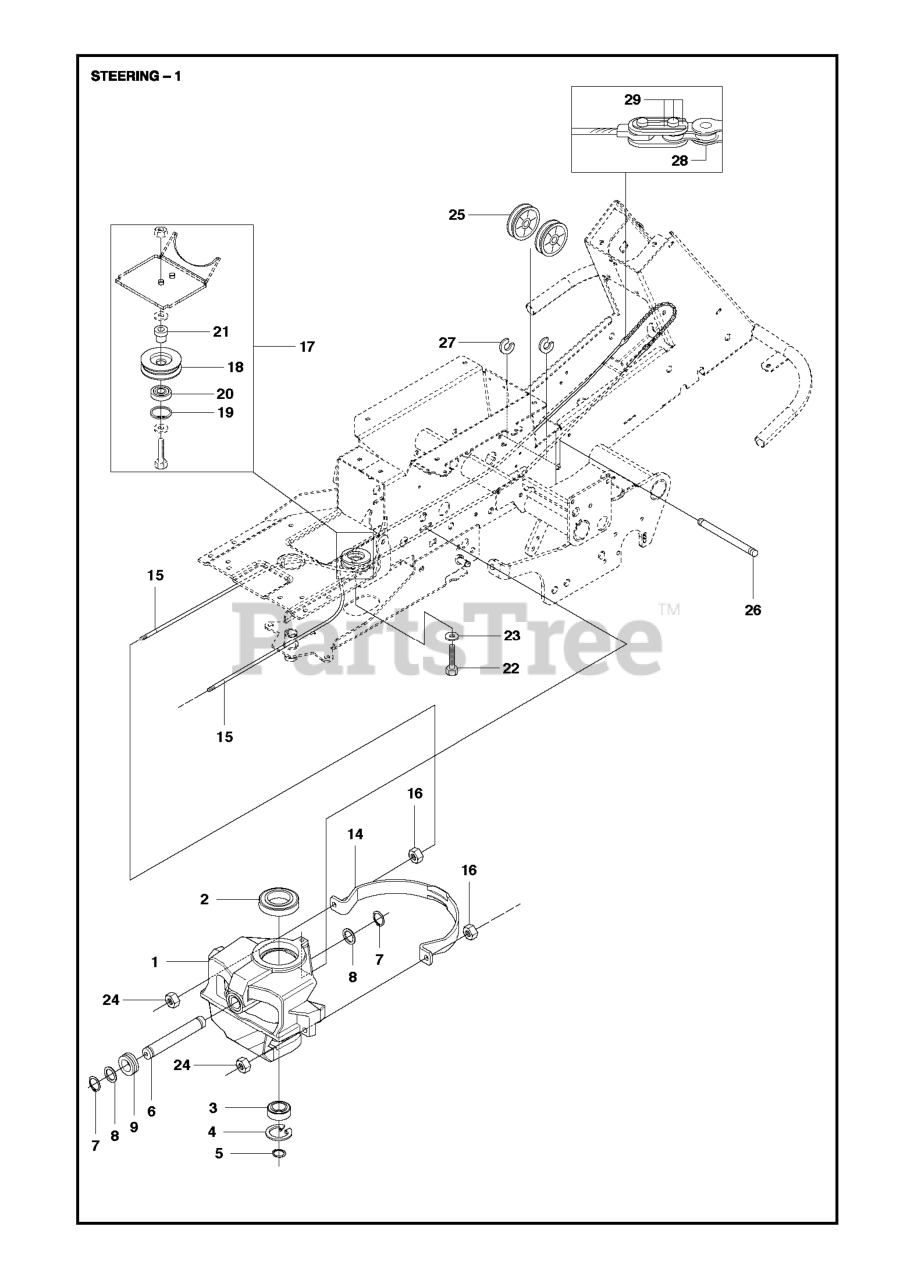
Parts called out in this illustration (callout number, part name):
1	TUBE HANDLE
2	BALL BEARING 6010 2RS1
3	Ball Bearing 6005-2rs
3	NUT T
4	CIRCLIP SGH 47
4	HANDLE.BAGGER.W/LVRS.BLK.CRD
5	RETAINING RING SGA 25
5	SCREW.PAN.HEAD
6	REPL BY 532 75 00-29
7	RETAINING RING SGA 25
8	COVER.PNT.BGR.CRD.WSLOTS.MS668
9	Bolt Carriage 1/4-20 x 2.25d x Gr.5
10	TUBE
11	BRACKET.SUPPORT.UPPER.BAG.CRD
12	BRKT PIVOT
14	WIRE GUIDE
14	BOLT-HEX EAK
15	RP STEERING CABLE COMPLETE
15	RETAINER-SPRNG RB
16	NUT
16	NUT LOCK FLG 3/8-16 UNC
17	RP BOLT 5/16-18 X3/4 ZN/YEL GR
19	CIRCLIP SGH 47
19	NUT LOCK HEX FLANGE 5/16-18
20	BALL-BEARING 6204-2RS
20	BRKT.PIVOT.RH.CRD
21	BAGGER.ASM.CRD.2007
22	REPL BY 725 25 00-71
22	BRKT.SIDE.BAG.CRD
24	NUT
24	TUBE.PIVOT.BAG.CRD.BLACK
25	PIPE
26	SHAFT
27	RETAINING RING
28	STEERING CHAIN
28	GRIP.HANDLE.BLACK
31	RETAINER CLIP
32	RIVET,DRILLED
33	PLUG.MULCHER.92 CRD
34	HANDLE.MULCHER.92.CRD (2 2)
36	WASHER
37	Plug Support Bagger CRD
38	BOLT.5/16-18X2.5
39	SEAL.BAGGER.CRD
41	BRKT.VERT.ADJ.BAGGER.CRD
43	PLUG, TUBING END
46	BOLT.CARRIAGE.5/16-18
47	PIPE
49	ROD
50	NUT.71038.31-18.HEX.NYLOCK
51	LATCH
53	NUT
54	BOLT
